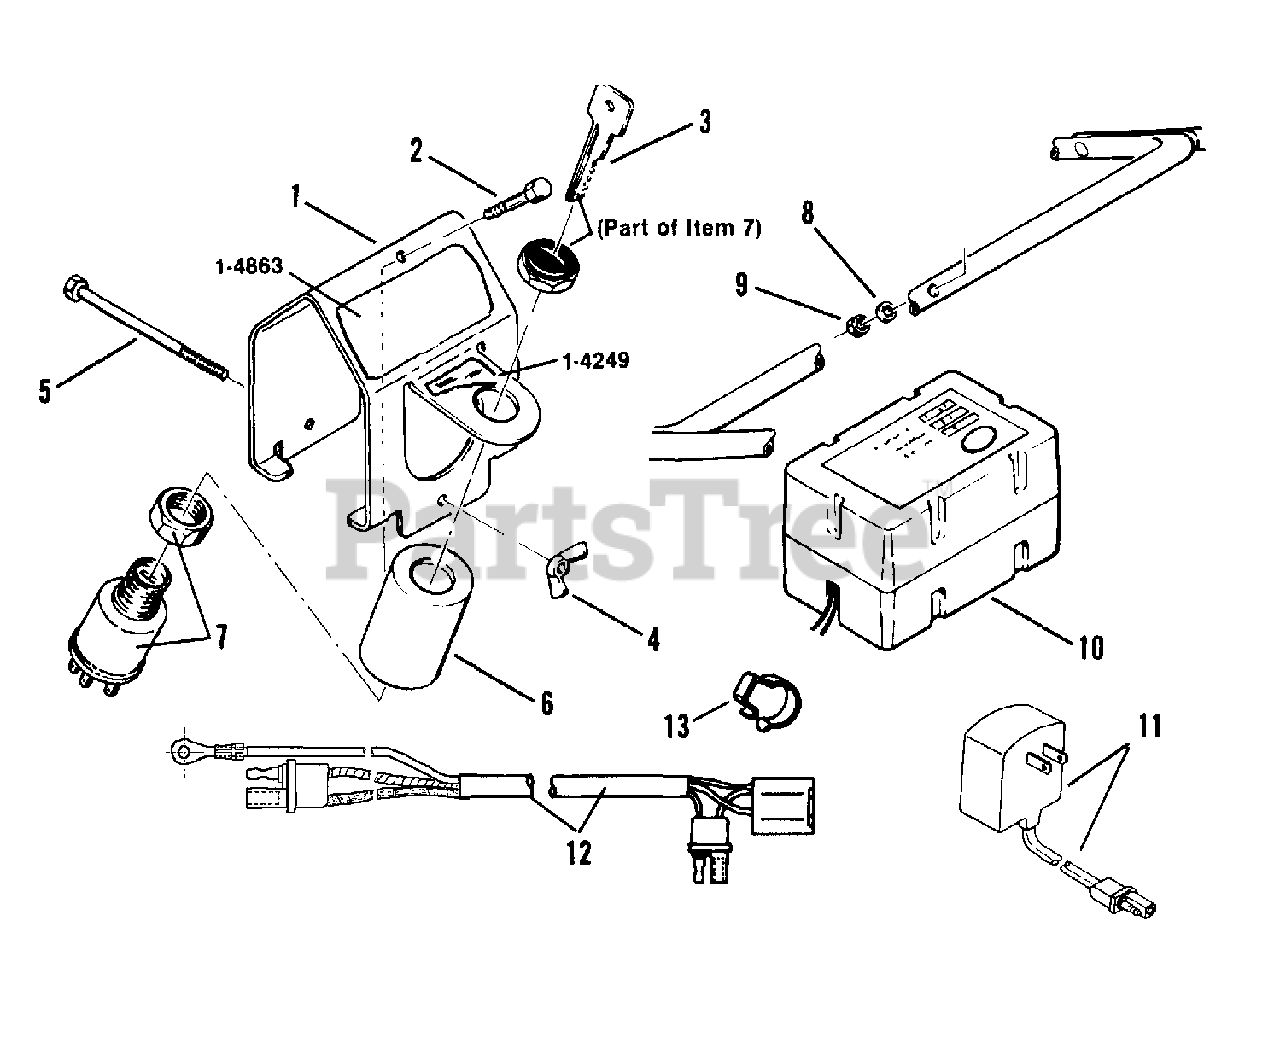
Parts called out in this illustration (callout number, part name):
1	BRACKET, ASSEMBLY (7037749 & 7014249)
2	CAPSCREW, 1/4F X 1-1/4
3	KEY, (Set of 2)
4	WING NUT 1/4F
5	CAPSCREW, 1/4F X 3-1/4
6	COVER, SWITCH
7	SWITCH, IGNITION
8	LOCKWASHER, 1/4 INTERNAL TOOTH
9	NUT, 1/4F HEX
10	BATTERY, 12 VOLT
11	CHARGER, BATTERY (60 HERTZ)
12	HARNESS, WIRING 48.5" (B&S)
13	CLIP, Wiring Harness
